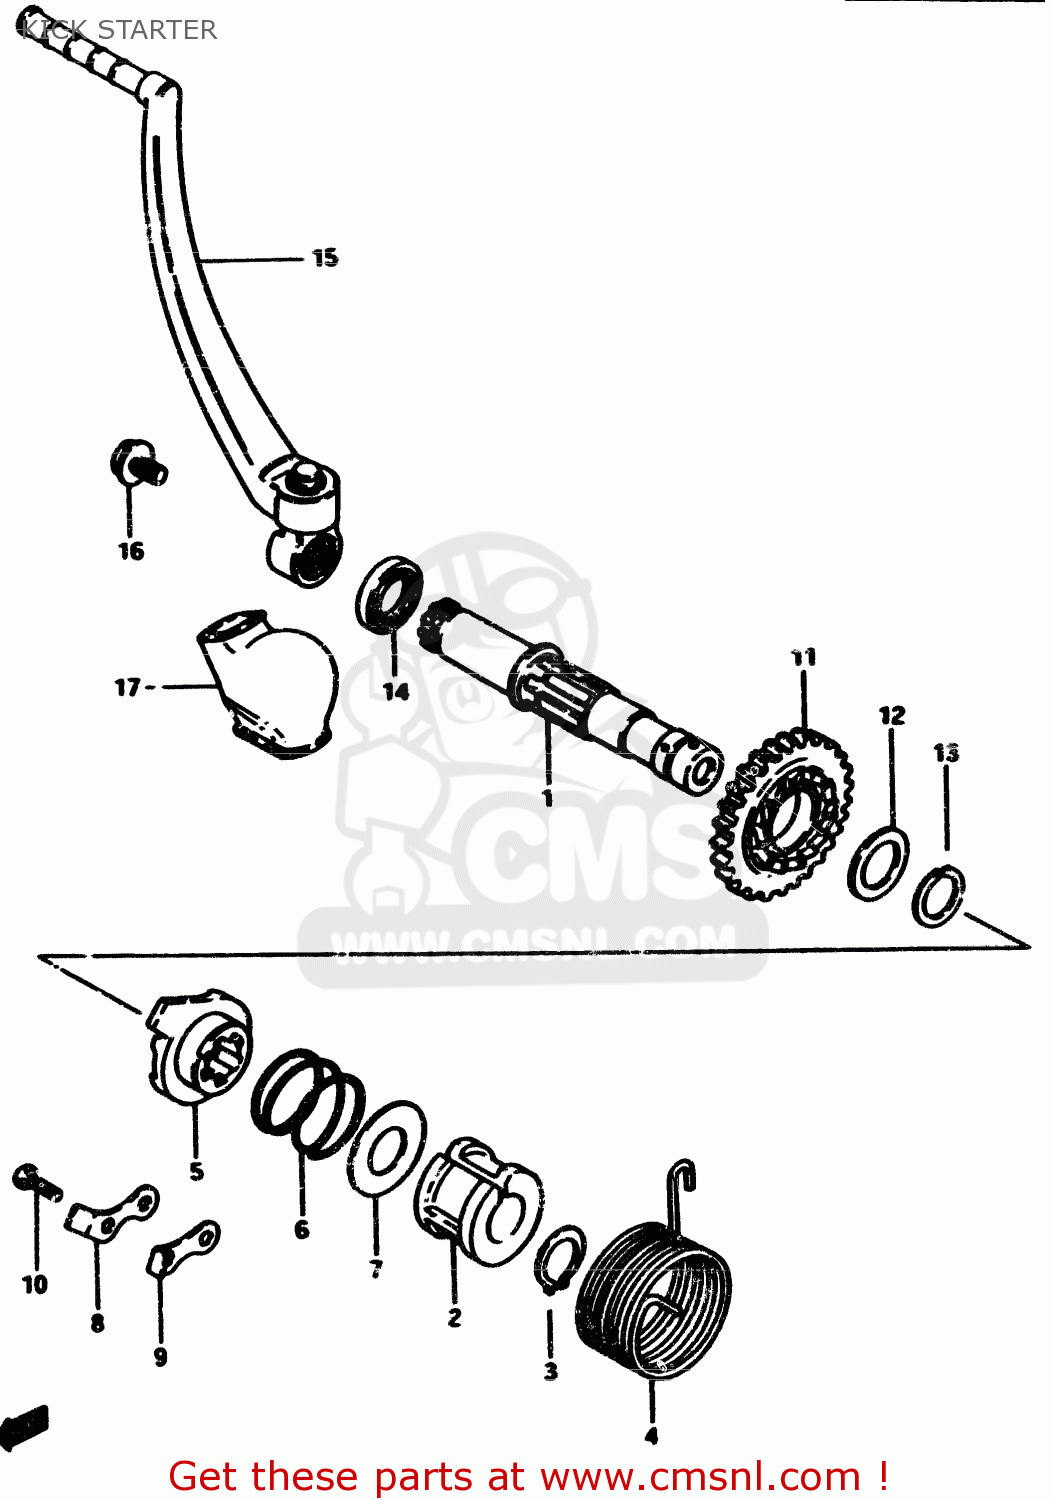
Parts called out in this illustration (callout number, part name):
1	SHAFT,KICK STARTER
2	GUIDE,KICK STARTER SFT SPRING
3	CIRCLIP
4	SPRING
5	STARTER,KICK
6	SPRING
7	WASHER
8	GUIDE,KICK STARTER
9	STOPPER,KICK STARTER
10	BOLT(8X20)
11	GEAR,KICK STARTER DRIVE
12	SHIM
13	CIRCLIP
14	SEAL,OIL(20X27X5)
15	LEVER ASSEMBLY,KICK STARTER
16	BOLT(8X14)
17	COVER,KICK STARTER LEVER JOINT
